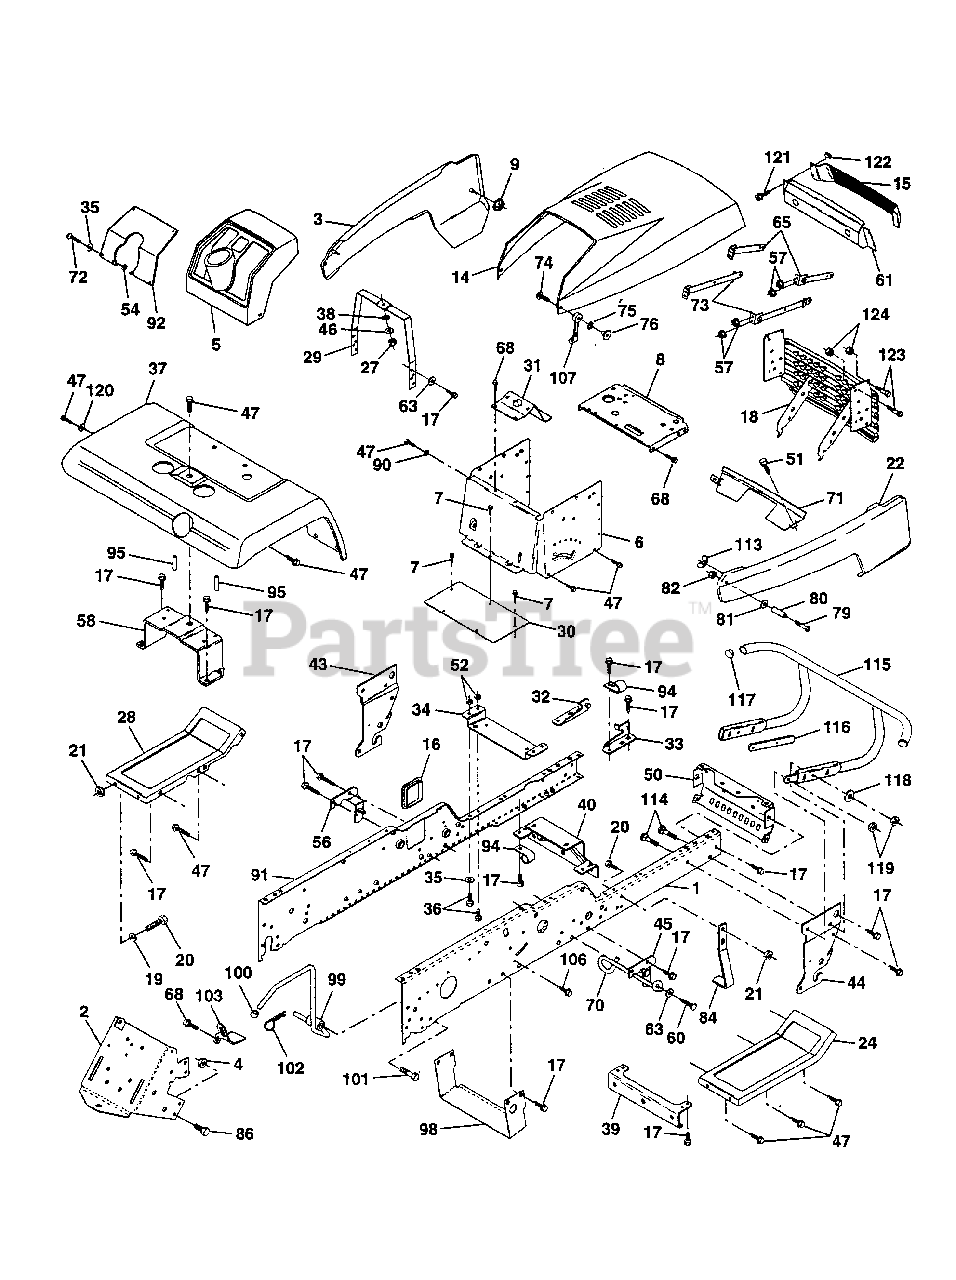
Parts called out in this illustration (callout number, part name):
2	DRAWBAR GT
4	NUT.7/16
5	DASHBOARD BLACK
6	DASH.1PC.LOWER
7	SCREW
8	SUPPORT.DASH.BTRY
9	PAL NUT LT
15	LENS LT
16	COVER ACCESS
17	SCREW
19	WASHER
20	BOLT
21	NUT
22	PANEL SIDE RH
24	FOOTREST.RH.LT/GT
28	FOOTREST.LH.LT/GT
29	DASH.SUPT.YP/HUSQ
30	SADDLE.HYDRO.95
31	BRAKET.SUPT.STEER
32	BRACKET ASM FRAME
33	BRACKET ASM FRAME
34	BRACKET.ENG.SUPT.
35	WASHER
36	BOLT
37	FENDER.PNT.
38	WASHER PM
39	BRACKET.AXLE.FRT.
43	BRACKET.SUS.FT.LH
44	BRACKET.SUS.FT.RH
46	LOCKWASHER
47	SCREW LT
50	BRACKET.CHASSIS.
51	SCREW CRT
57	NUT
58	BRKT.ASM.FENDER
60	SCREW
63	WASHER
68	SCREW LT
69	SHIELD.HEAT.MUF
70	GUIDE.BELT.MID.SP
71	STRAP.GRILLE.PNT.
72	SCREW
74	SCREW
75	LOCKWASHER
76	WELDNUT
79	SCREW
80	SPACER LT
81	WASHER
84	STOP.OVER.CENTER
86	BOLT
90	LOCKWASHER
92	PLATE YP SLKSCR
94	CLIP GTV
95	NUT-PUSH YT
98	BRACKET SKID CHAS
99	ROD BYPASS
101	SCREW LT
102	RETAINER M
103	LOCK BYPASS BRKT
107	HOOD LATCH T
114	BOLT.3/8-14X1.25
115	BUMPER.ASM.W/PY
116	BRACKET.EXT.BUMP.
117	PLUG.PLASTIC
118	WASHER
120	WASHER HYT
122	"""J"" FASTENER LT"
124	NUT
